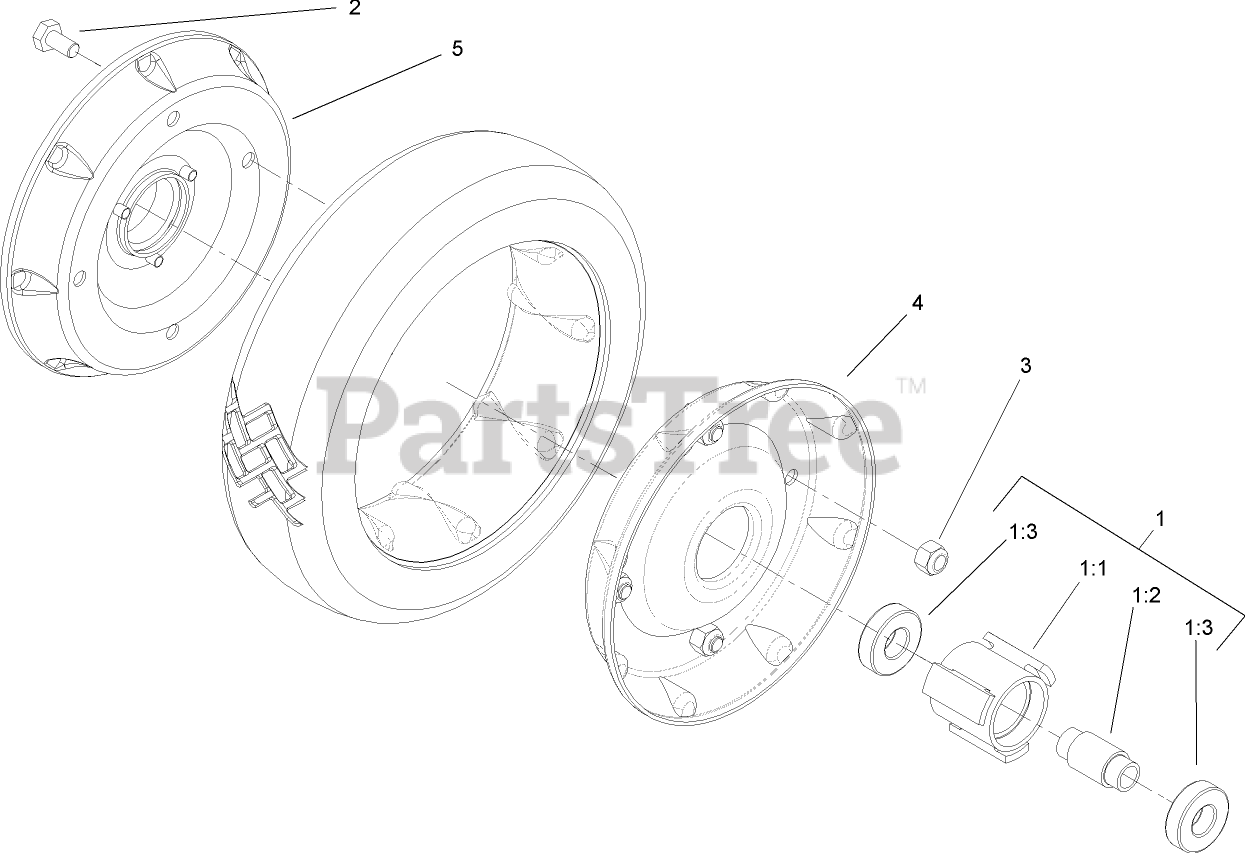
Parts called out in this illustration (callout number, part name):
1	Loose Parts Package
1:1	HUB-BEARING
1:2	SPACER-BEARING
1:3	BEARING-WHEEL
2	SCREW-HH
3	NUT-LOCK, NI
